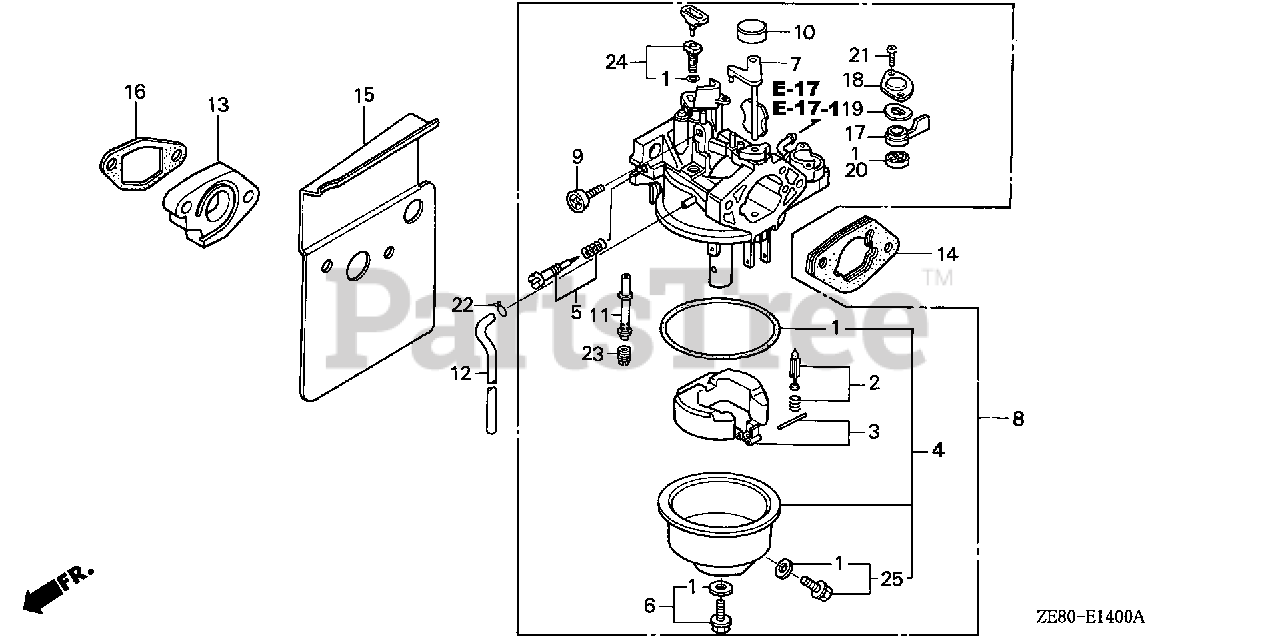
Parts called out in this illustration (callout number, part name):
1	GASKET SET (CARBURETOR NO.)
1	GASKET SET (CARBURETOR NO.) (EXCEPT 16173-001-004)
2	VALVE SET, FLOAT
4	CHAMBER SET, FLOAT
5	SCREW SET, PILOT
6	SCREW SET
7	CHOKE SET (CARBURETOR NO.)
8	CARBURETOR ASSY. (BE23A C)
8	CARBURETOR ASSY. (BE23A E/F)
9	SCREW, THROTTLE STOP
10	CAP, CHOKE DUST (CARBURETOR NO.)
11	NOZZLE, MAIN
12	TUBE, AIR VENT (75MM)
13	INSULATOR, CARBURETOR
14	SPACER, CARBURETOR
15	GASKET, CARBURETOR
16	GASKET, INSULATOR (NOT AVAILABLE)
17	LEVER, PETCOCK (CARBURETOR NO.)
18	PLATE, LEVER SETTING (CARBURETOR NO.)
19	SPRING, PETCOCK LEVER
20	GASKET, PETCOCK (CARBURETOR NO.)
21	SCREW, PAN (3X8)
22	CLIP, TUBE (B8)
23	JET, MAIN (#80) (CARBURETOR NO.)
23	JET, MAIN (#82) (CARBURETOR NO.)
23	JET, MAIN (#85) (CARBURETOR NO.)
24	JET SET, PILOT (#45)
